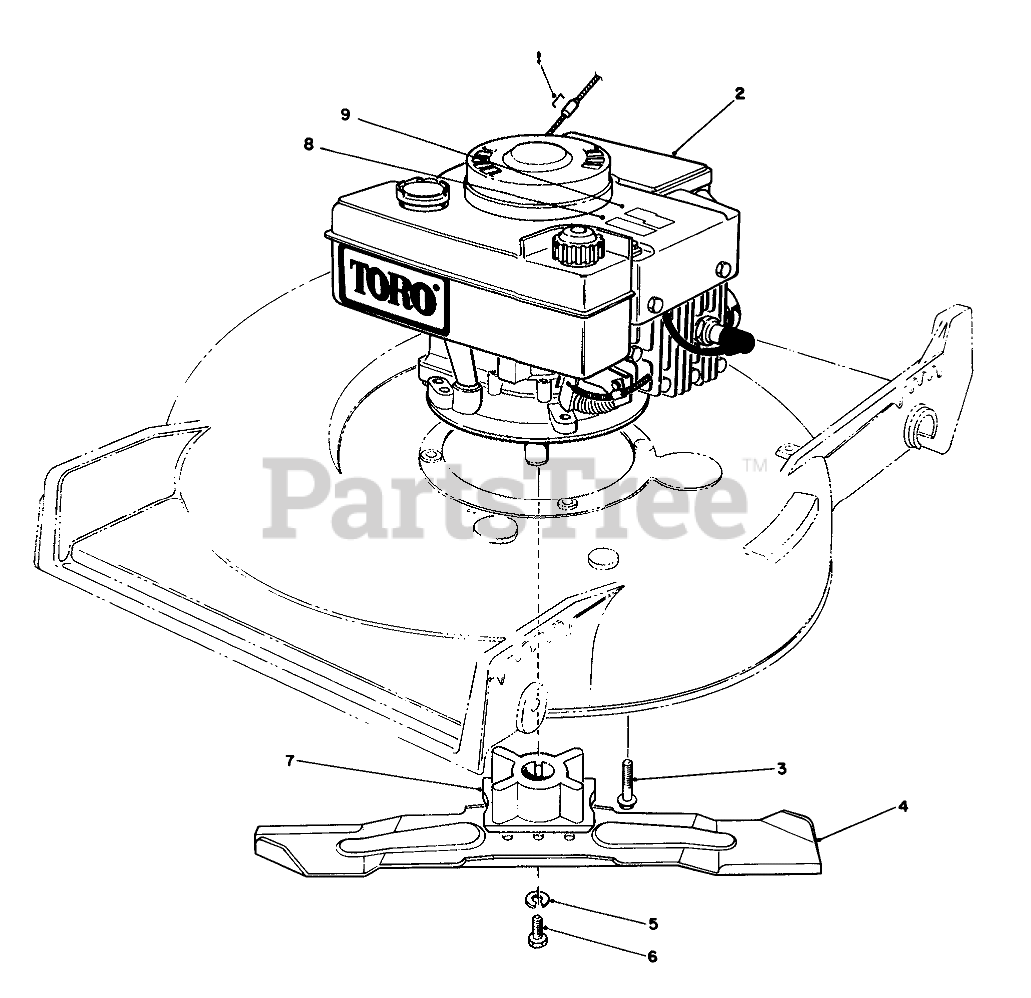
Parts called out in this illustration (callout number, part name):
1	Staple
3	3/8-16 X 2 CAPSCREW
4	BLADE-21in
5	WASHER-LOCK
6	SCREW-BLADE
7	BLADE RETAINER
8	Decal-Features
9	ENGINE DECAL
